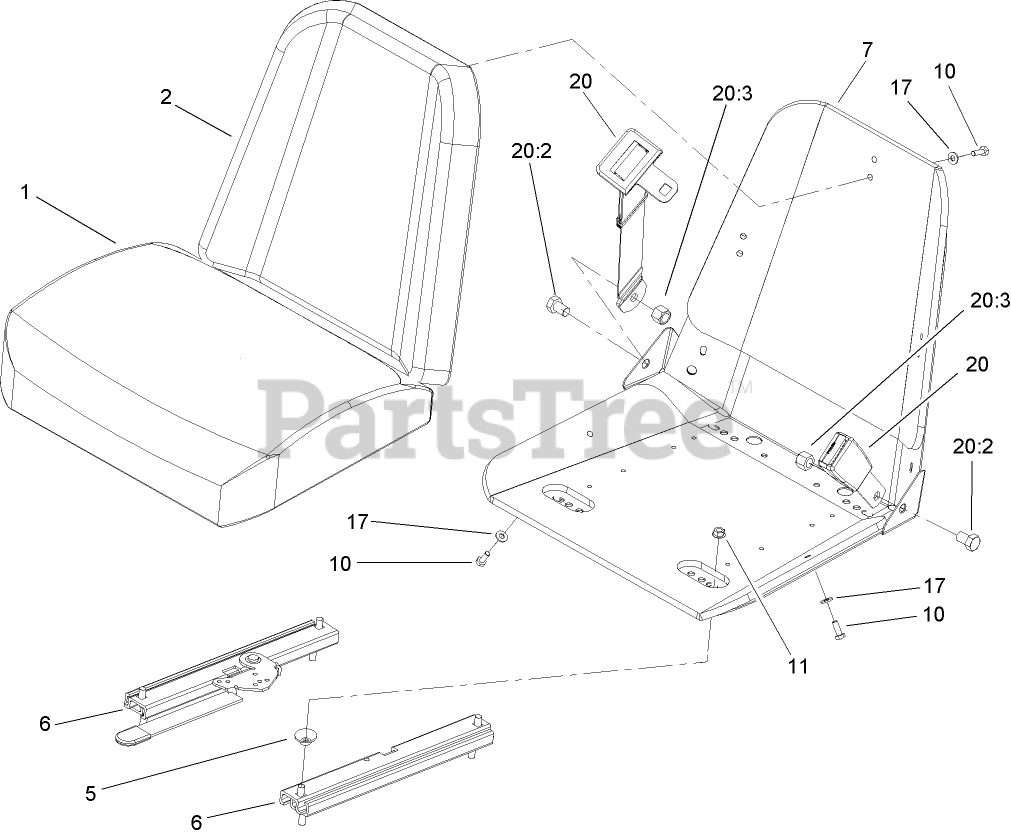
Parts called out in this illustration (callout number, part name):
1	CUSHION-SEAT, BOTTOM
2	CUSHION-SEAT, BACK
5	SPACER-TRACK
6	TRACK-SEAT
7	FRAME-SEAT
10	SCREW-HH
11	NUT-HF
17	WASHER-FLAT
20	SEATBELT KIT
20:2	SCREW-HH
20:3	NUT-LOCK, NI
